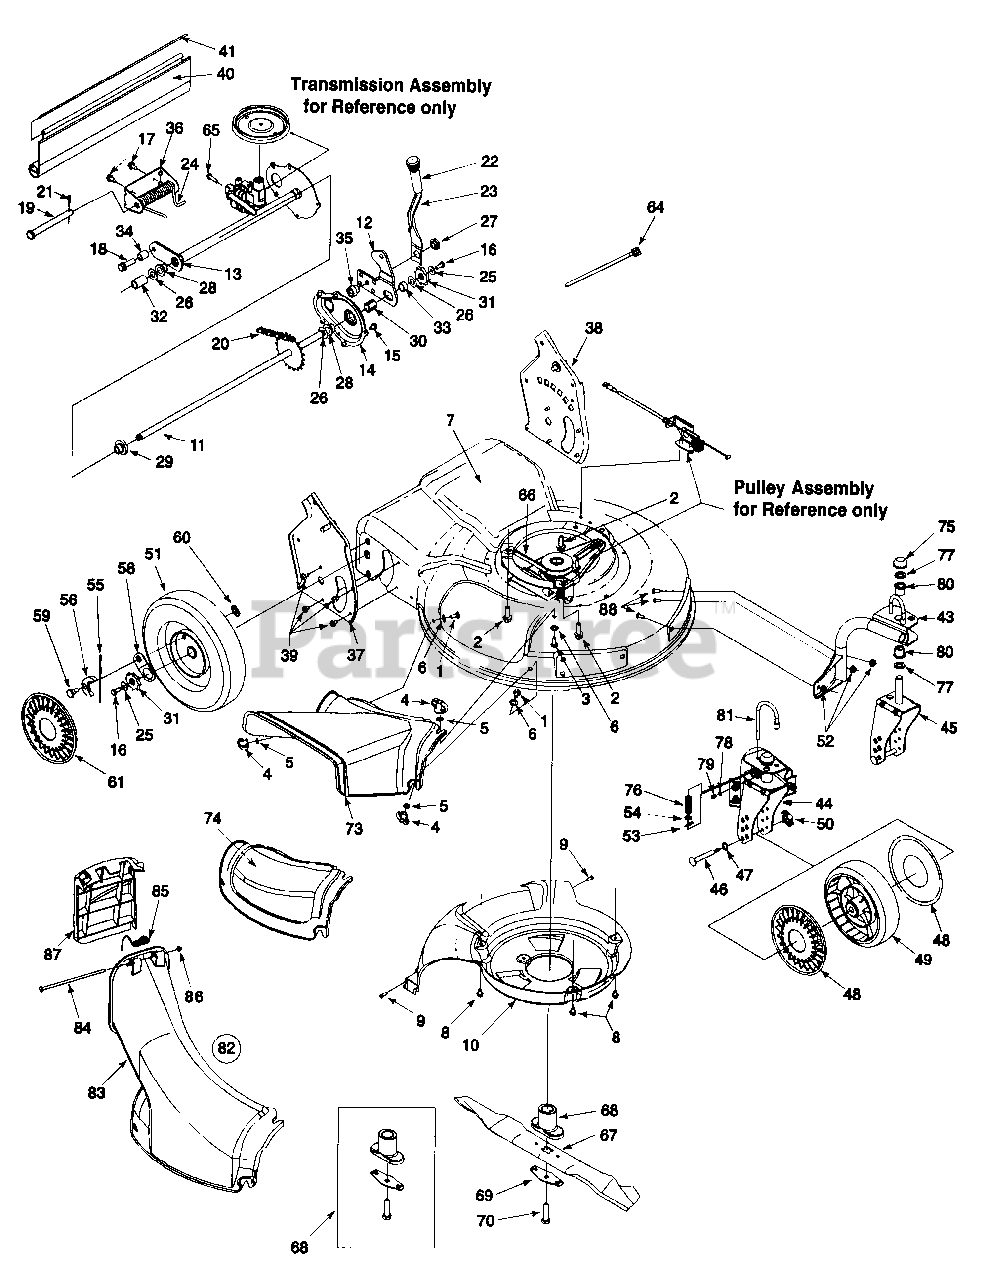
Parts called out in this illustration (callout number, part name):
1	Scr. Carr. 1/4-20 x .62
2	Scr. TT:3/8-18:1.00
3	Carriage Scr. 1/4-20 x .750
4	Wing Nut 1/4-20
5	Nut, Push .25 I.D. x .50 O.D.
6	Wash. Fl. .334 I.D. x .62 x .03
9	Scr. HL. 1/2-14 x .750
10	Baffle
11	Rear Axle Assembly
16	Cap Screw HH 1/4-20 x .620
17	Scr. AB 1/4-20 x .625
18	Scr. 3/8 116 x .25
19	Clevis Pin .50 Dia. x 4.82
20	Chain-Endls. #48 .500P x 24L
21	Cotter Pin .125 O.D. x .75
23	Spring Lever
24	Torsion Spring
25	Bell Wash. .285 x .75 x .082
26	Fl. Wash. .508 I.D. 1.000 x.020
27	Nut Shld. .825 Dia. x .165
28	Hx. Flg. Brg. .506 I.D. x .590
29	Hx. Flg. Brg. .506 I.D. x.715
30	Hx. Slv. Brg. .504 I.D. x .830
31	Wheel Rachet
32	Spa. .550 I.D. x /750 O.D.
33	Spa. .51 .D. x .70 O.D. x 38 L.
34	Spa. .385 x .624 x .700
35	Shld. Spa. .385 I.D. X .715 Lg.
40	Trail Shield
41	Trail Shield Wire
46	Caster Axle .374 Dia x 2.50"
47	Wave Washer
48	Hub Cap, Yellow w/ hole
49	Wheel 7 x 2 Link
50	Wing Nut 1/4-20
51	Wheel 9 x 2 Link
52	Lock Nut 5/15-18
53	Cotter Pin .072 x .12
54	Fl. Wash. .330 x .830 x .060
55	Spring, Ratchet, Plastic
56	Pawl - R.H.
56	Pawl - L.H.
58	Ratchet Pawl Plate
59	Scr. Shld. .340 x .285
60	Top Lock Tab Weld Nut 1/4-20
63	Casing Clamp, Throttle
64	Cable Tie
65	Hex Scr. 5/16-18
66	Belt, 3/8" x 39.24"
67	21" Mulching Blade
68	Blade Adapter
69	Blade Bell Support
70	Hex Bolt 3/8-24 x 2.5"
73	Side Discharge Chute
74	Mulch Cover
75	Push Cap
76	Compression Spring
77	Fl. Wash. .5/8 I.D. x 1" O.D.
78	Fl. Wash. .203 x .403 x .
79	Fitting - Grease
80	Flange Bearing
81	Locking Pin
82	Chute Ass'y
83	Discharge Chute
84	Pivot Rod
85	Torsion Spring
86	Push Cap
87	Chute Door
88	Carr. Bolt 5/16-18 x .62
